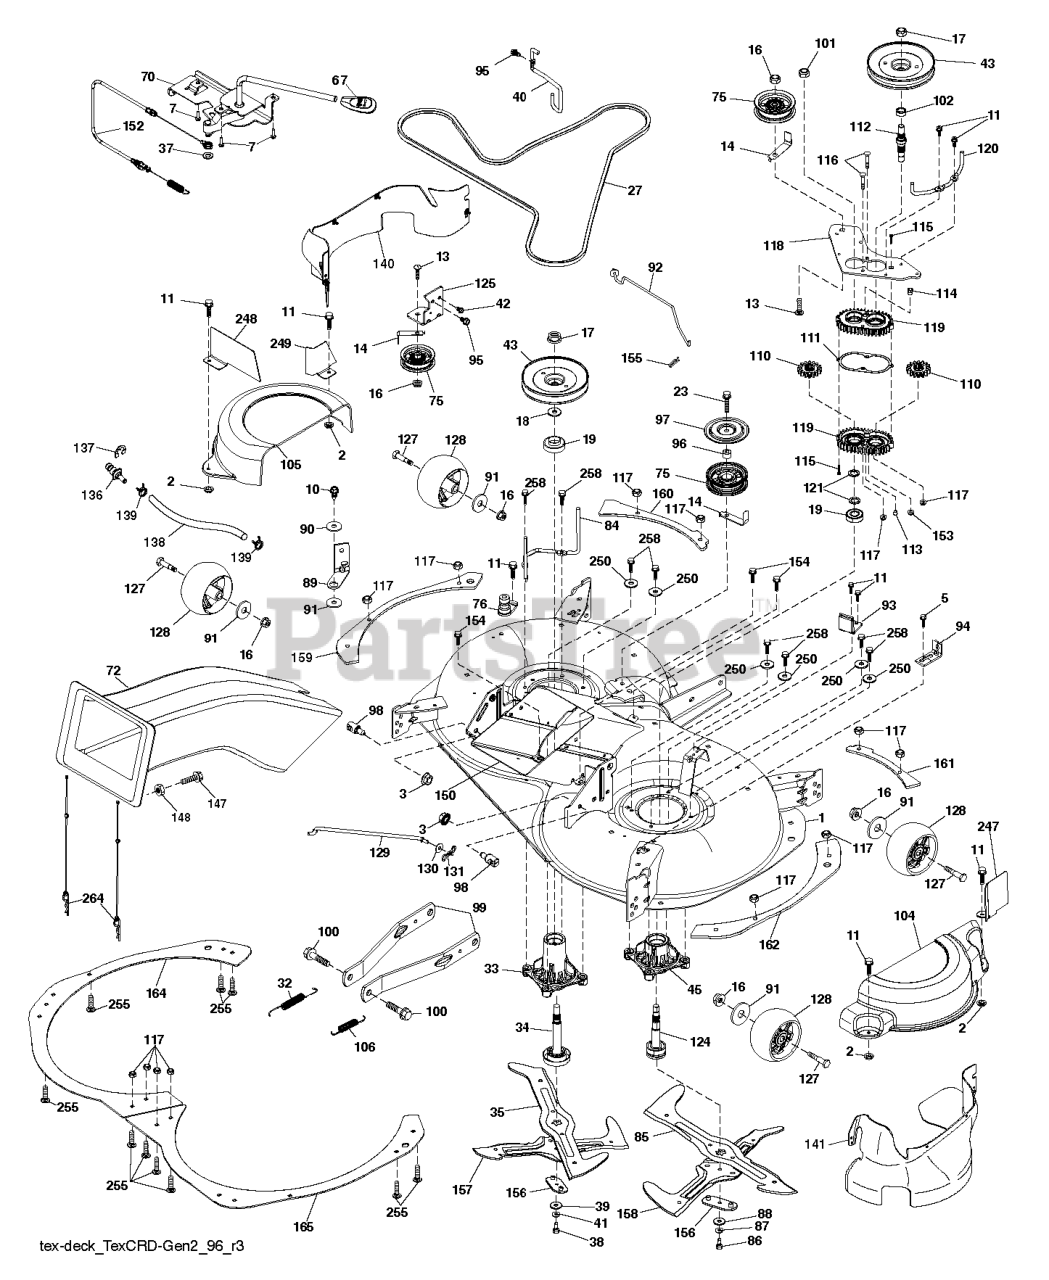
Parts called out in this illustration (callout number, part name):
1	DECK SVCX.107HP.C.BL.498
2	PALNUT 1/4
3	NUT LOCK HEX FLANGE 5/16-18
5	BOLT.5/16HEX.WHS.HD
7	SCREW.#10 X 0.750.BOS
10	SCREW 3/8-16X1
11	SCREW.1/4-20X5/8
13	BOLT.3/8-16X1.50
14	KEEPER, BELT IDLER
16	NUT LOCK FLG 3/8-16 UNC
17	NUT.FLANGE.LOCK.TOP
18	WASHER.SPACER.MANDREL
19	BEARING.MANDREL.TOP.EXTENDED
23	SCREW LT
27	BELT BELT. MOWER DRIVE 97.4 EL
32	SPRING RETURN
33	RP.HOUSING.MANDREL.4PT.
34	SHAFT ASM.MNDRL.N/GREASEABLE
35	BLADE.3N1.LH.CRD
37	WASHER
38	BOLT.BLADE.7/16-20 X 1.5 GR8
39	WASHER.7/16.FLAT
40	KEEPER BELT ENGINE LH
41	WASHER 7/16 LOCK
42	SCREW
43	PULLEY PULLEY MANDREL 5.438 PD
45	HOUSING.MANDREL.44/46" VENT
67	HANDLE.CLUTCH.CABLE.LT
70	CLUTCH.ASM.MANUAL.YT.PREDATORQ
72	CHUTE.SLOTTED.HOLES.TEX.CRD.II
75	FLAT IDLER PULLEY
76	1/2" BARB.DECK.WASHOUT.PORT
84	KEEPER KEEPER. LH MANDREL BELT
85	BLADE.3N1.RH.CRD
86	BOLT.3/8-24X1.25GR8. LHTHRD
87	SLW 3/8 STD
88	WASHER.BLADE
89	ARM BRAKE MOWER
90	SPACER.RETAINER
91	WASHER
92	ROD ASM BRAKE ROD 107 TEX CRD
93	ARM.BRAKE.97.RH
94	BRKT.CLUTCH.CABLE
95	SCREW, 3/8-16X3/4
96	SPACER
97	PROTECTOR
98	STUD.FASTNER.W/ANTI-ROTATE
99	ARM.SUSPENSION.MOWER.R
100	BOLT.SHOULDER
101	NUT.CROWNLOCK.9/16 -18.UNC
102	SPACER BEARING
104	COVER.MANDREL.107.RH.GEN.2
105	COVER.MANDREL.107.LH.GEN.2
106	SPRING.BRAKE.RETURN.38"
110	CRD.SPUR.GEAR
111	GASKET GASKET GEARCASE
112	SHAFT SHAFT. CRD GEARCASE ADAP
113	PLUG PLUG OIL
114	VENT.BREATHER.1/8 NPT
115	SCREW
116	BOLT.CARIGE.SS.1/4-20X1.75GR5
117	NUT T
118	ARM ARM. CLUTCHING 107 TEX CRD
119	GEARCASE GEARCASE SUBASM
120	KEEPER KEEPER. RH MANDREL BELT
121	WASHER WASHER
124	MANDREL SHAFT NON/GREASE
125	BRACKET BRACKET IDLER CHASSES
127	BOLT.SHOULDER.3/8-16X3-5/8.
128	WHEEL.GAUGE.RALLY
129	ROD ROD. SWAY CRD GEN II
130	WASHER
131	PIN.COTTER.5/16.BOW TI
136	PLUG WASHOUT PORT HOOKUP
138	107.WASHOUT.PORT.HOSE (2 2)
139	HOSE.3/8.CLAMP (2 2)
140	GUARD.ASSEMBLY.107.LH.FRENCH
141	GUARD.ASSEMBLY.107.RH.FRENCH
147	BOLT CROSS DRILLED CUP HEAD SQ
148	NUT.HEX.3/8-16
150	CHUTE LOWER.WLDT.107.CRDII
152	CABLE CABLE CLUTCH ASSEMBLY
153	NUT HEXAGON 9/16-18 G2 ZPB LOC
154	SCREW T-30 1/4-20 X
155	RETAINER M
156	ADAPTER ADAPTER.CROSSBLADE.107
157	BLADE 107CM.CROSS.BLADE
158	BLADE.CROSS.RH.CRD.107
159	REINFORCE.PLATE.LHS.BOLT.431
160	REINFORCE.PLATE.LH.FT.X431
161	REINFORCE.PLATE.RH.FRT.X431
162	REINFORCE.PLAT.RH.SD.BLT.X431
164	BAFFLE.PLATE.PNT.107CRD.LT.BLK
165	BAFFLE.PNT.107.CRD.PLATE.RT.BK
247	GUARD BELT.CRD.RH.ISO X431 BLA
248	GUARD.STEEL.CRD.MANDREL.COV.FR
249	GUARD.STEEL.CRD.MANDREL.COV.FR
255	RHSNB, 1/4-20 X 1, GR5
258	BOLT.HEX.WASHR.HED.313-18X1.19
264	RETAINER.ASM.UPPERCHUTE.CRD2.5
